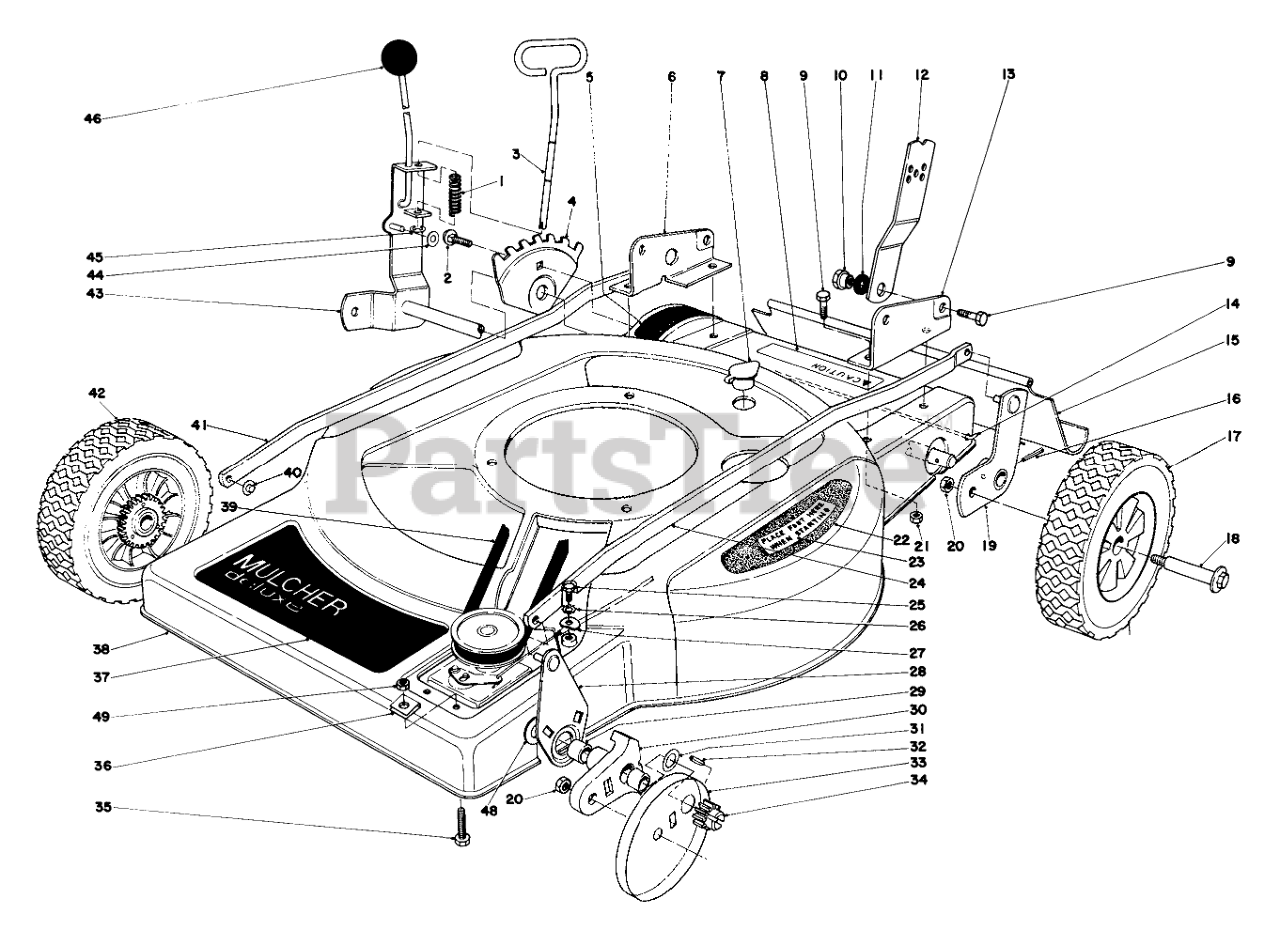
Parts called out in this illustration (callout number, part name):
1	Spring Compression
2	Carriage Bolt
3	Rod Stop
4	HOC ADJUSTMENT PLT
5	Decal Height of Cut
6	Bracket Handle R.H.
7	Plug Washout
8	Caution Decal
9	SCREW-HH
10	HANDLE PIVOT NUT
11	SPACER
12	Handle Latch
13	Bracket Handle L.H.
14	SHIELD ROD
15	SHIELD - TRAILING
16	Pin-Special
17	WHEEL TIRE ASM 8 IN
18	BOLT-WHEEL
19	Pivot Arm Rear L.H.
20	Nut
21	NUT-LOCK, CONE
22	PAD STEP
23	Decal Step Pad
24	Spanner Link L.H.
25	SCREW-HH
26	WASHER-LOCK/EXT
27	CLAMP-BODEN
27	WASHER
28	PIVOT ARM LINK WA
29	BUSHING
30	Pivot Arm (Incl. Ref. #29)
31	WASHER-THRUST
32	PIN-GROOVED
33	WHEEL COVER
34	Pinion
35	SCREW
36	SPEED NUT
37	Decal-Front Deck
38	Housing
39	V BELT
40	NUT-SPEED
41	Spanner Link R.H.
42	Wheel & Tire Assembly
43	Pivot Arm Bracket
44	WASHER-FLAT
45	E-RING
48	WASHER
49	NUT-LOCK
